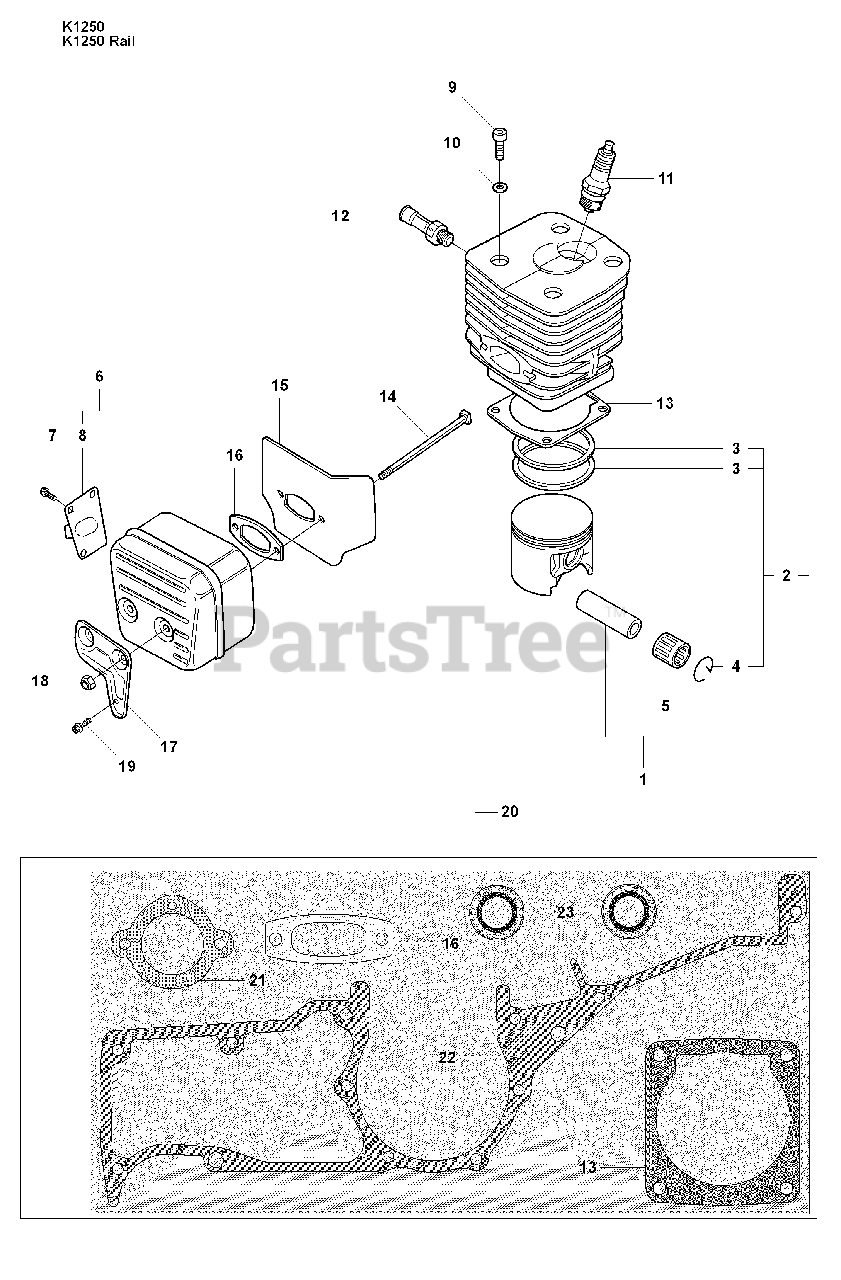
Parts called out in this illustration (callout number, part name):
1	CYLINDER
2	PISTON CPL
3	PISTON RING
5	SUPPORT BUSHING
6	MUFFLER
8	EXHAUST DUCT
10	WASHER STEEL
11	SPARK PLUG
12	DECOMPRESSION VALVE
13	GASKET
15	COOLING PLATE
16	GASKET MUFFLER
17	MUFFLER SUPPORT
20	GASKET KIT
21	GASKET
22	CRANKCASE GASKET
23	SEALING RING
